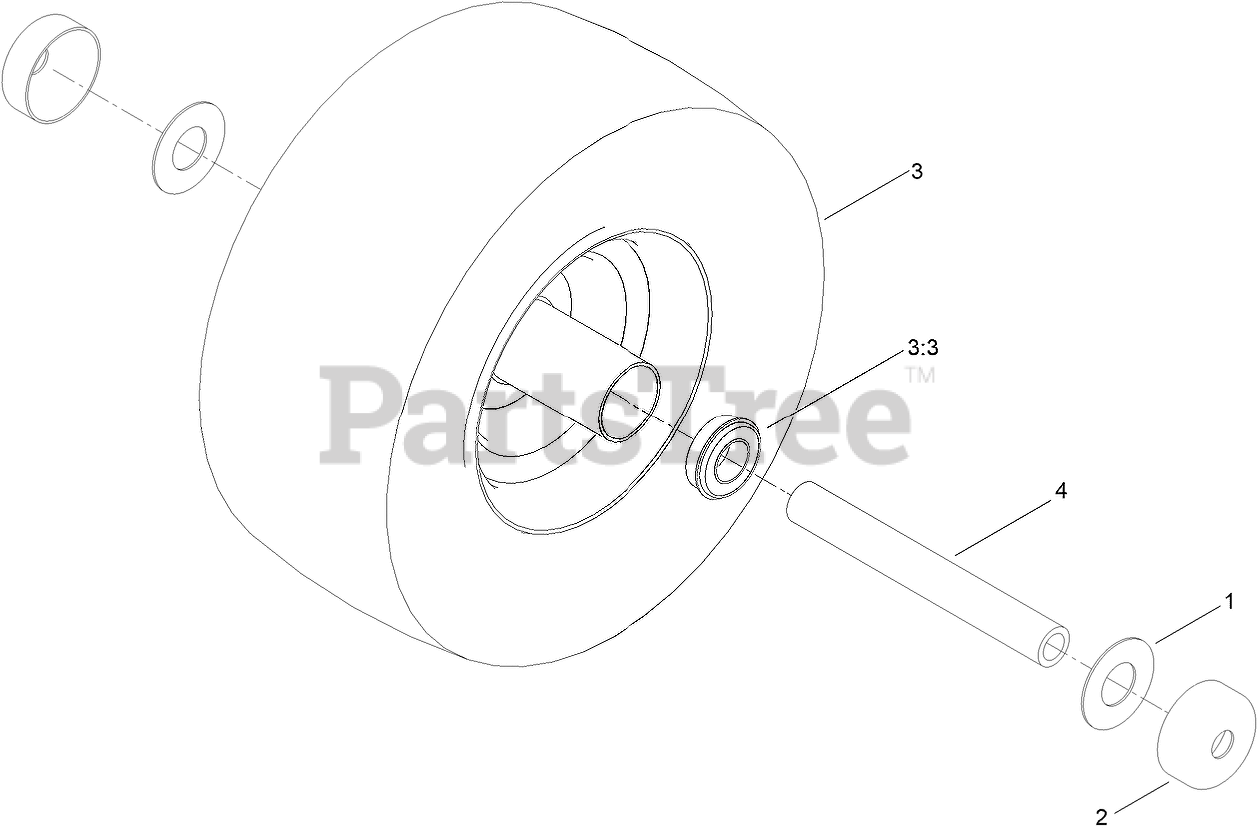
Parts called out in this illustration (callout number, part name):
1	WASHER
2	GUARD-SEAL
3	TIRE AND WHEEL ASM
3:3	BEARING
4	SPACER-SPANNER
